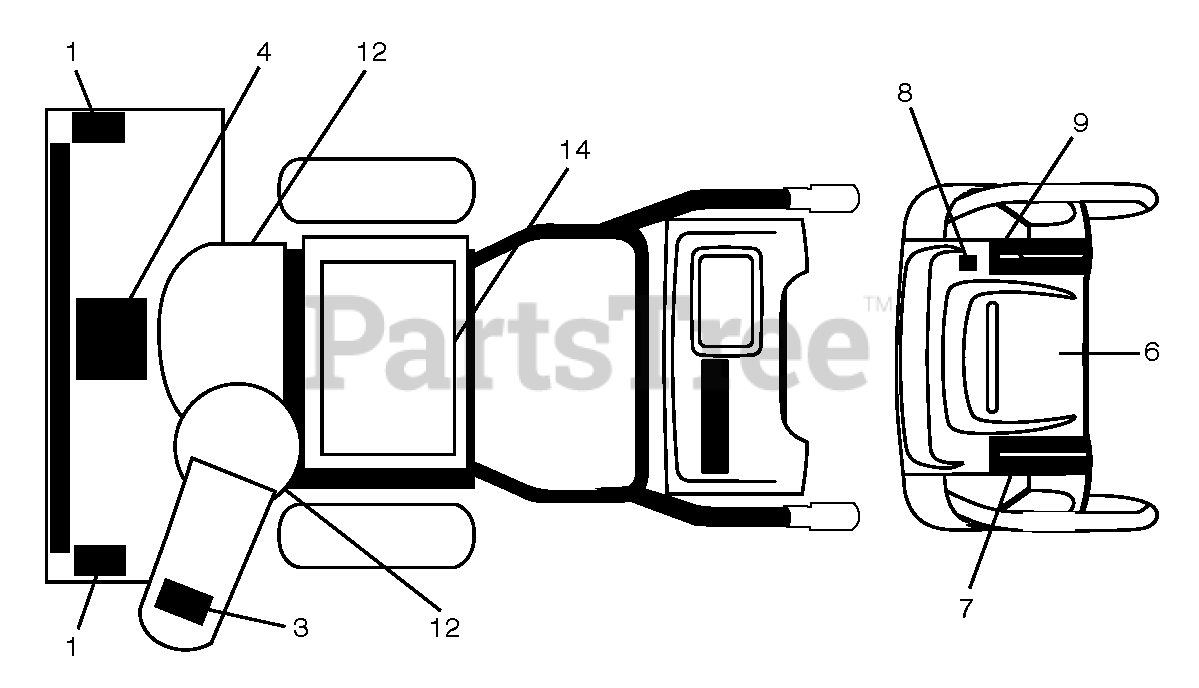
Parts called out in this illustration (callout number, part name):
1	DECAL.AUGER.SAFETY.
3	DECAL.CHUTE.SAFETY.
4	DECAL.AUGER."
7	DECAL.CONS.LH.REMOTE.INST.GRY
8	DECAL.CONSOLE.HAND.WARMER
9	DECAL.CONS.RH.INST.GRY
12	DECAL.BELT.GUARD.
14	DECAL.FENDER
